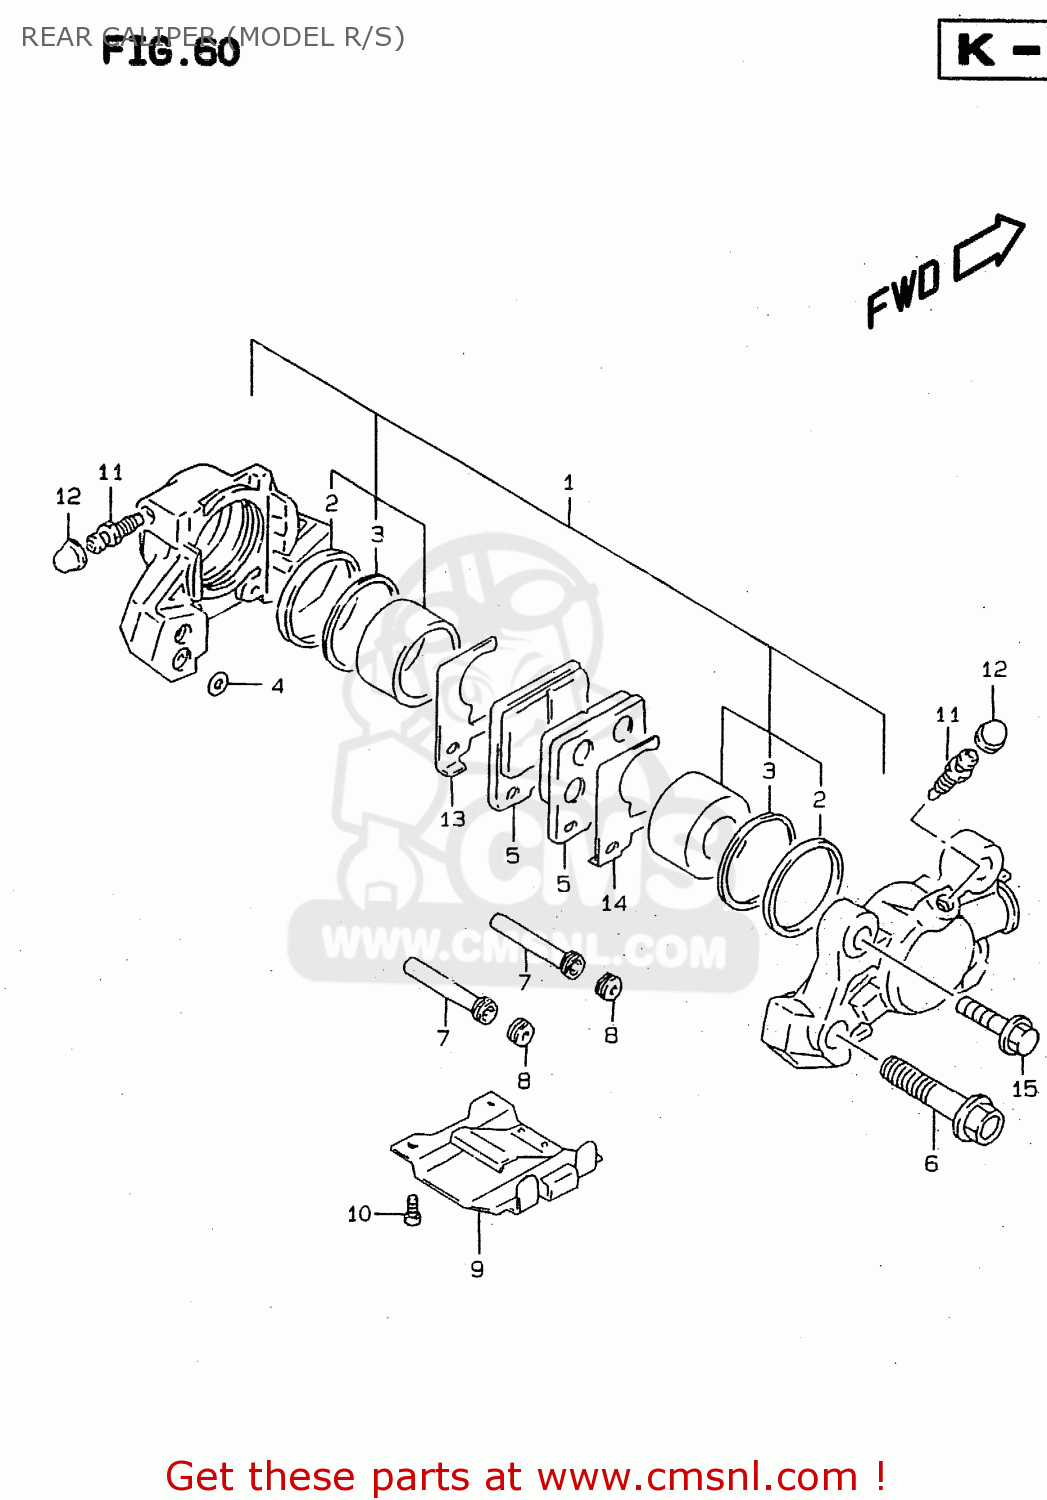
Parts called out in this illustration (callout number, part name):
1	PISTON SET
2	SEAL,PISTON
3	SEAL,WIPER
4	SEAL,JOINT
5	PAD,BRAKE
6	BOLT
7	PIN,PAD
8	PLUG,PAD PIN
9	COVER
10	SCREW
11	BLEEDER
12	CAP,BREATHER
13	SHIM,PAD,INNER
14	SHIM,PAD,OUTER
15	BOLT
